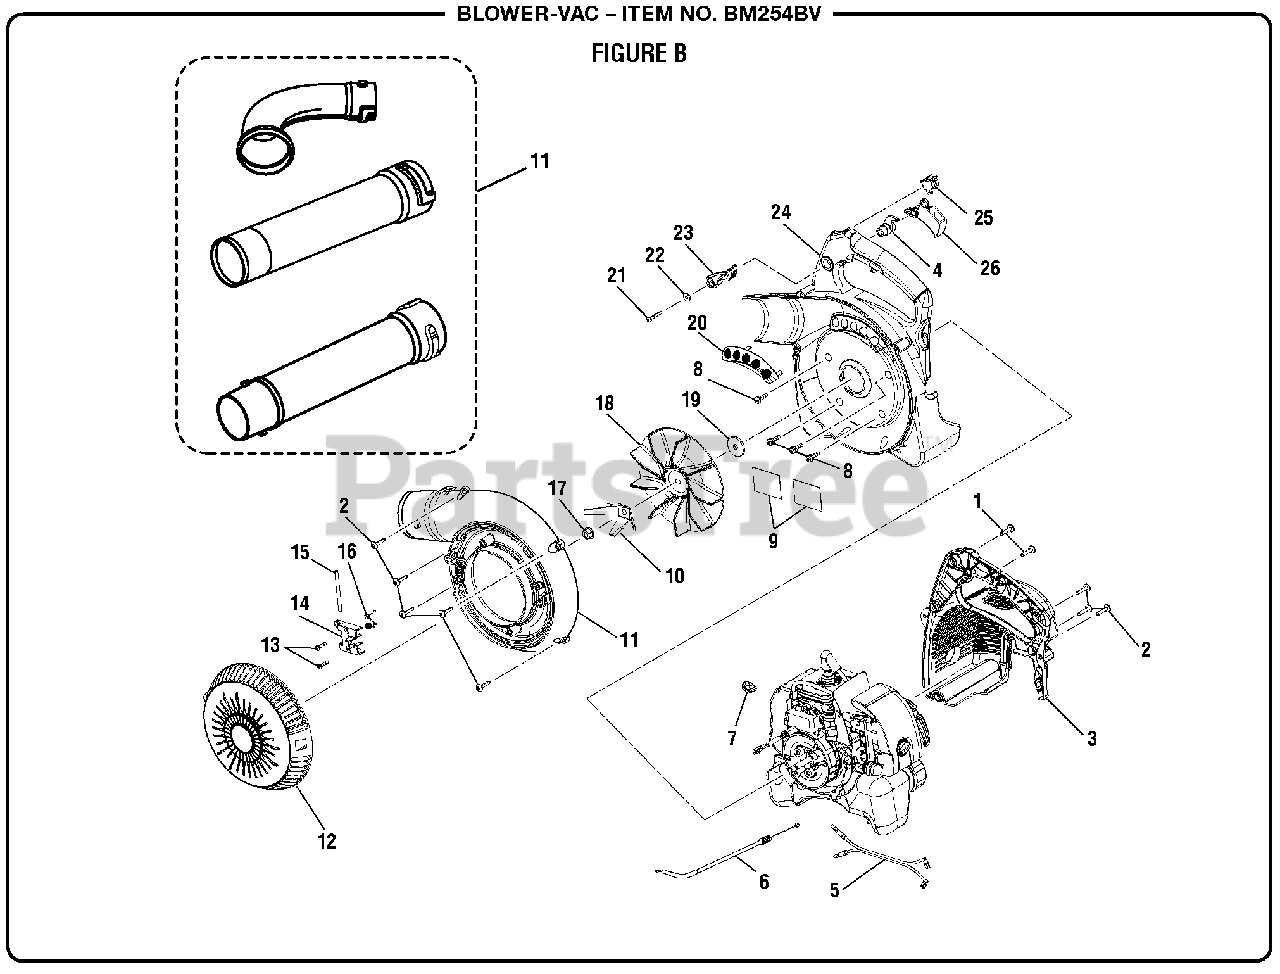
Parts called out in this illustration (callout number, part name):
1	Screw (10-14 x 7/8 in., T25 Torx T.F.)
2	Screw (10-14 x 7/8 in., T25 Torx Pan Hd. T.F.)
3	Engine Shroud w/Label
4	Throttle Lock (Cruise Control)
5	Wiring Harness
6	Throttle Cable
7	Rubber Grommet
8	Screw w/Washers (M5 x 20 mm, T25 Torx Pan Hd.)
9	Heat Shield Tape
10	Mulcher Blade
11	Housing and Tube Assembly Kit
12	Vacuum Door w/Label
13	Screw (8-14 x 5/8 in., Pan Hd.)
14	Vacuum Door Hinge
16	Hinge Spring
17	Lock Nut (M8 x 1.25, Flange Hd.)
19	Washer (ID9.8 x OD30 x 3t)
20	Mesh Screen
21	Screw (8-14 x 1 in., Special T20 Torx Truss Hd. T.F.)
22	Washer (ID4.3 x OD12 x 1.5t)
23	Cruise Control Lever
24	Engine Switch
25	Throttle Trigger
